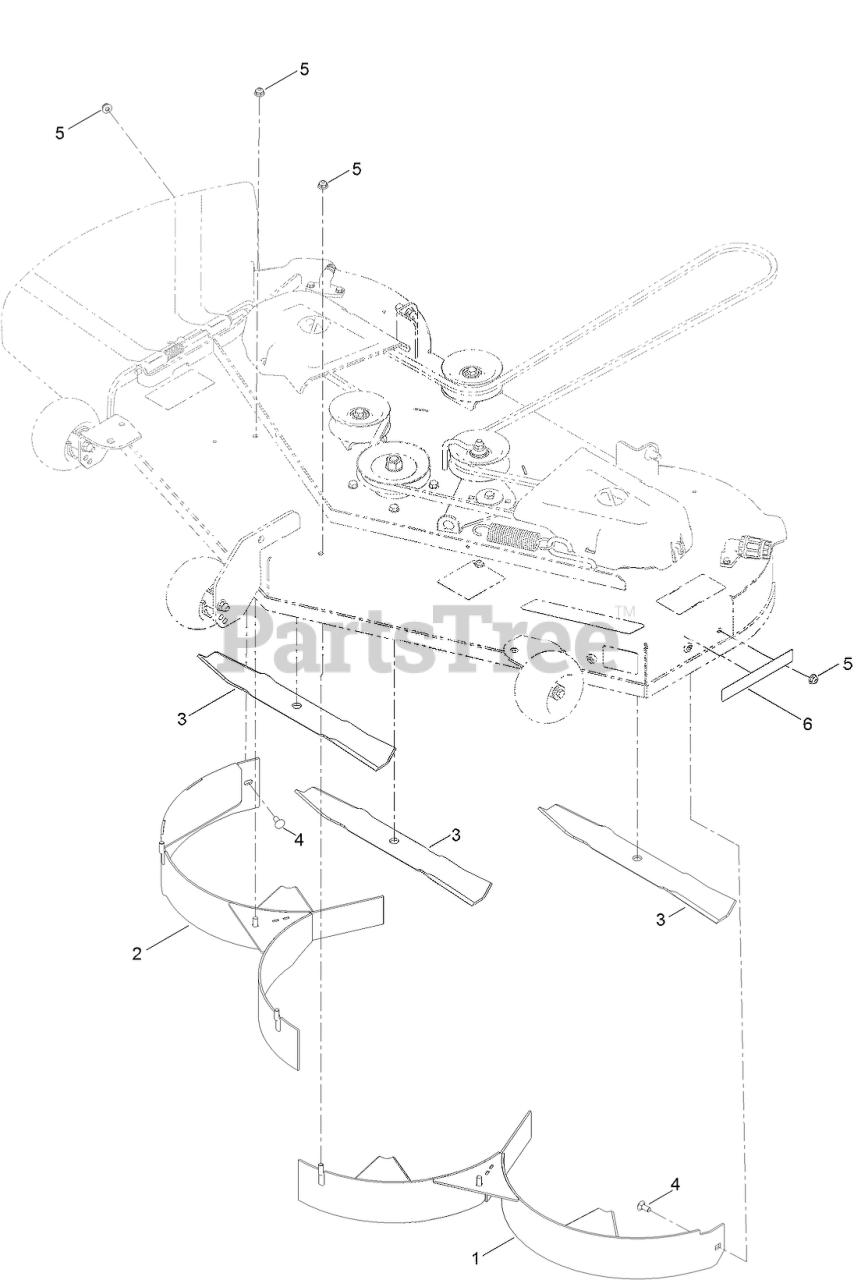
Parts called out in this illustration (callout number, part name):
1	50IN BAFFLE ASM
2	50IN BAFFLE ASM
3	BLADE-MULCH, 17.50 INCH
4	BOLT-CARR
5	NUT-HF
6	DECAL-RECYCLER
